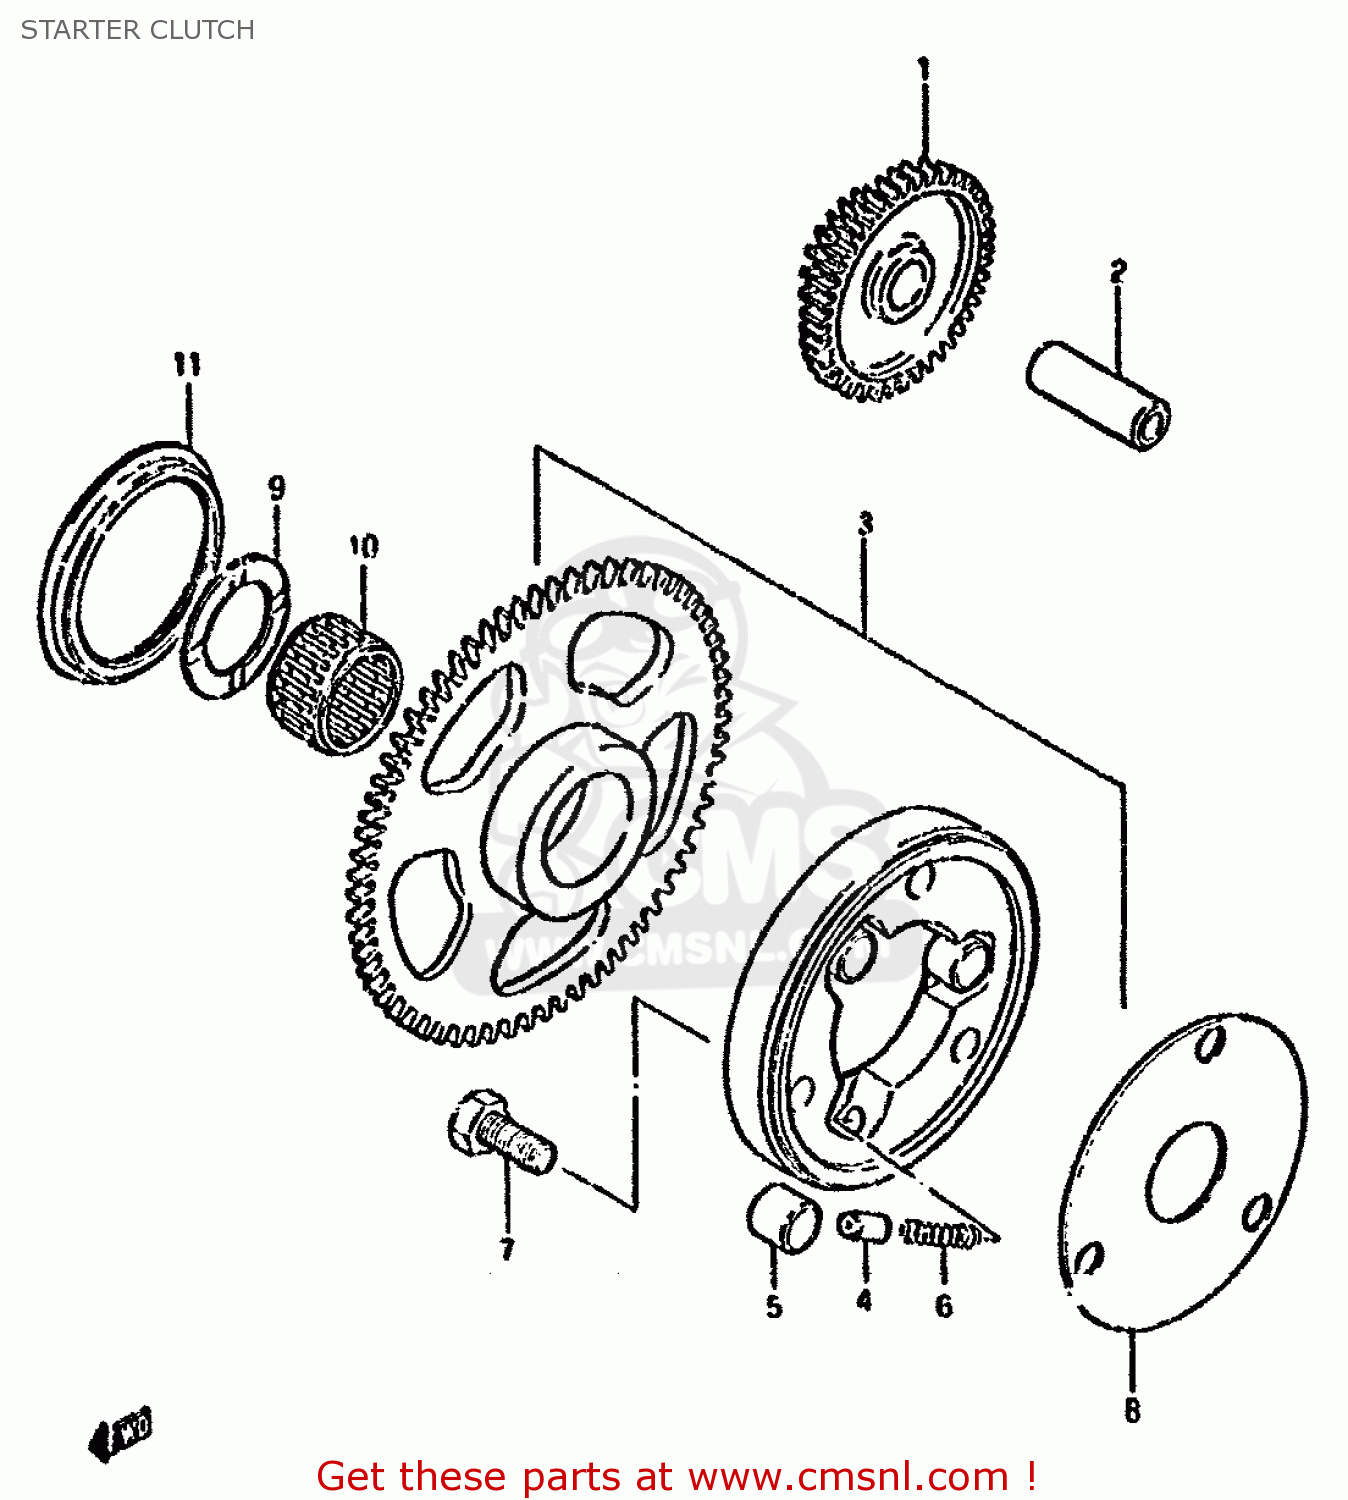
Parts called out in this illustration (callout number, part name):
1	GEAR,STARTER IDLE
2	PIN(7.4X13X40)
3	CLUTCH SET,STARTER
4	PIECE,PUSH
5	PIN(14X13)
6	SPRING
7	BOLT
8	SHIM,STARTER CLUTCH HUB
9	WASHER(27X40X2.5)
10	BEARING(27X32X21.8)
11	SEAL,OIL(52X62X6.8)
